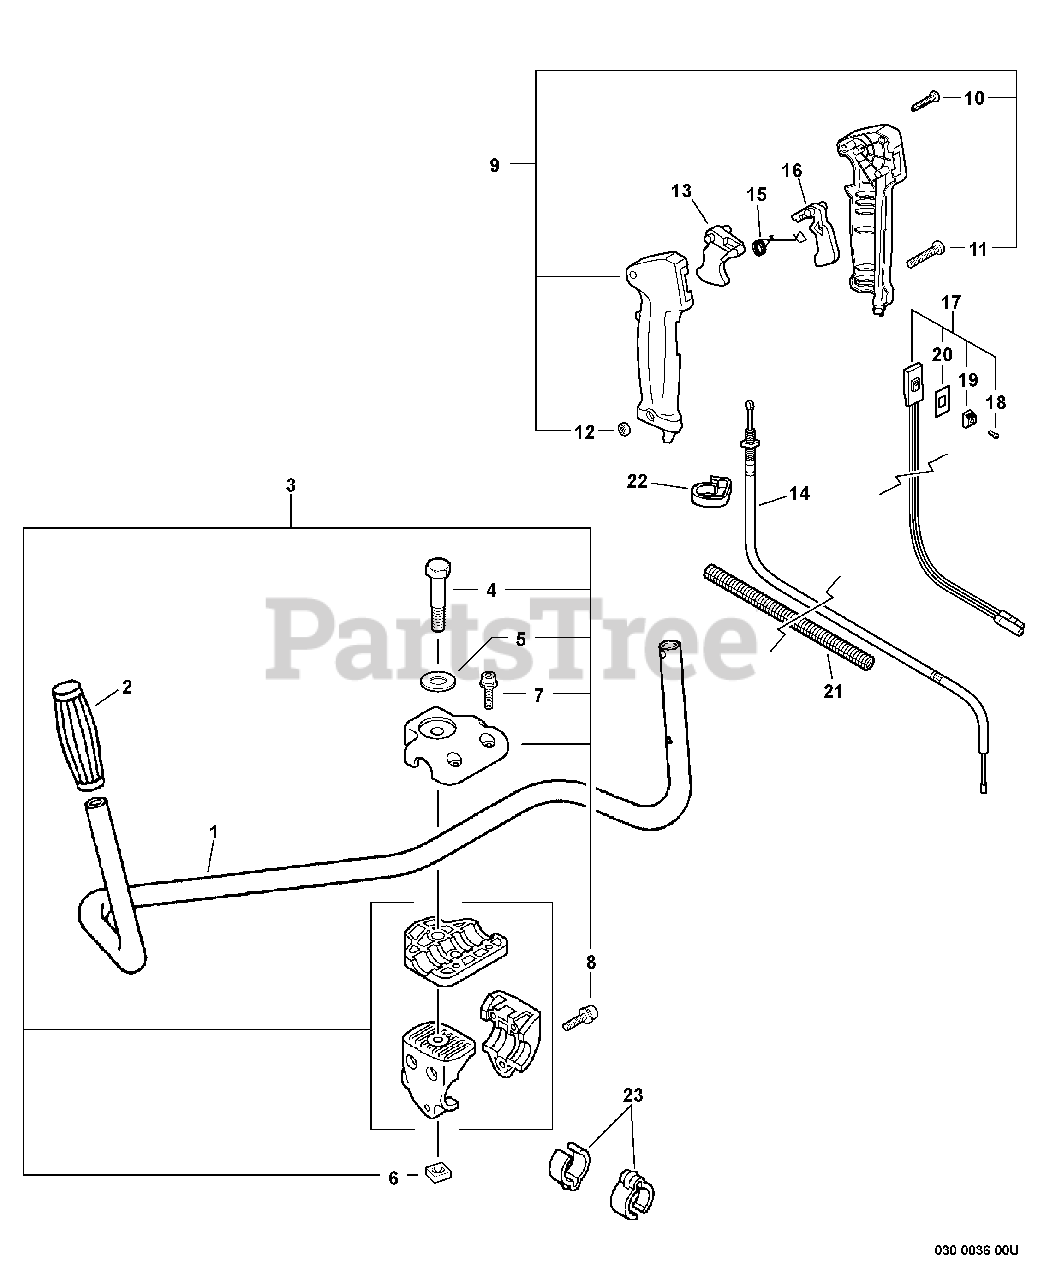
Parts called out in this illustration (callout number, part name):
1	HANDLEBAR
2	GRIP, HANDLE
3	BRACKET KIT, HANDLEBAR
4	BOLT 8×55
5	WASHER 8
6	NUT 8×1.25
7	BOLT 5×20
8	BOLT 5×30
9	CONTROL HANDLE KIT
10	SCREW 3×25
11	SCREW 5×30
12	NUT M5
13	TRIGGER, THROTTLE
14	CABLE, THROTTLE
15	SPRING, TORSION
16	LOCKOUT, THROTTLE
17	SWITCH, ON-OFF
18	SCREW 3×10
19	KNOB, SWITCH - ORANGE
20	LABEL, SWITCH
21	TUBE, FLEXIBLE 7×790
23	CLIP, CABLE 25 MM
